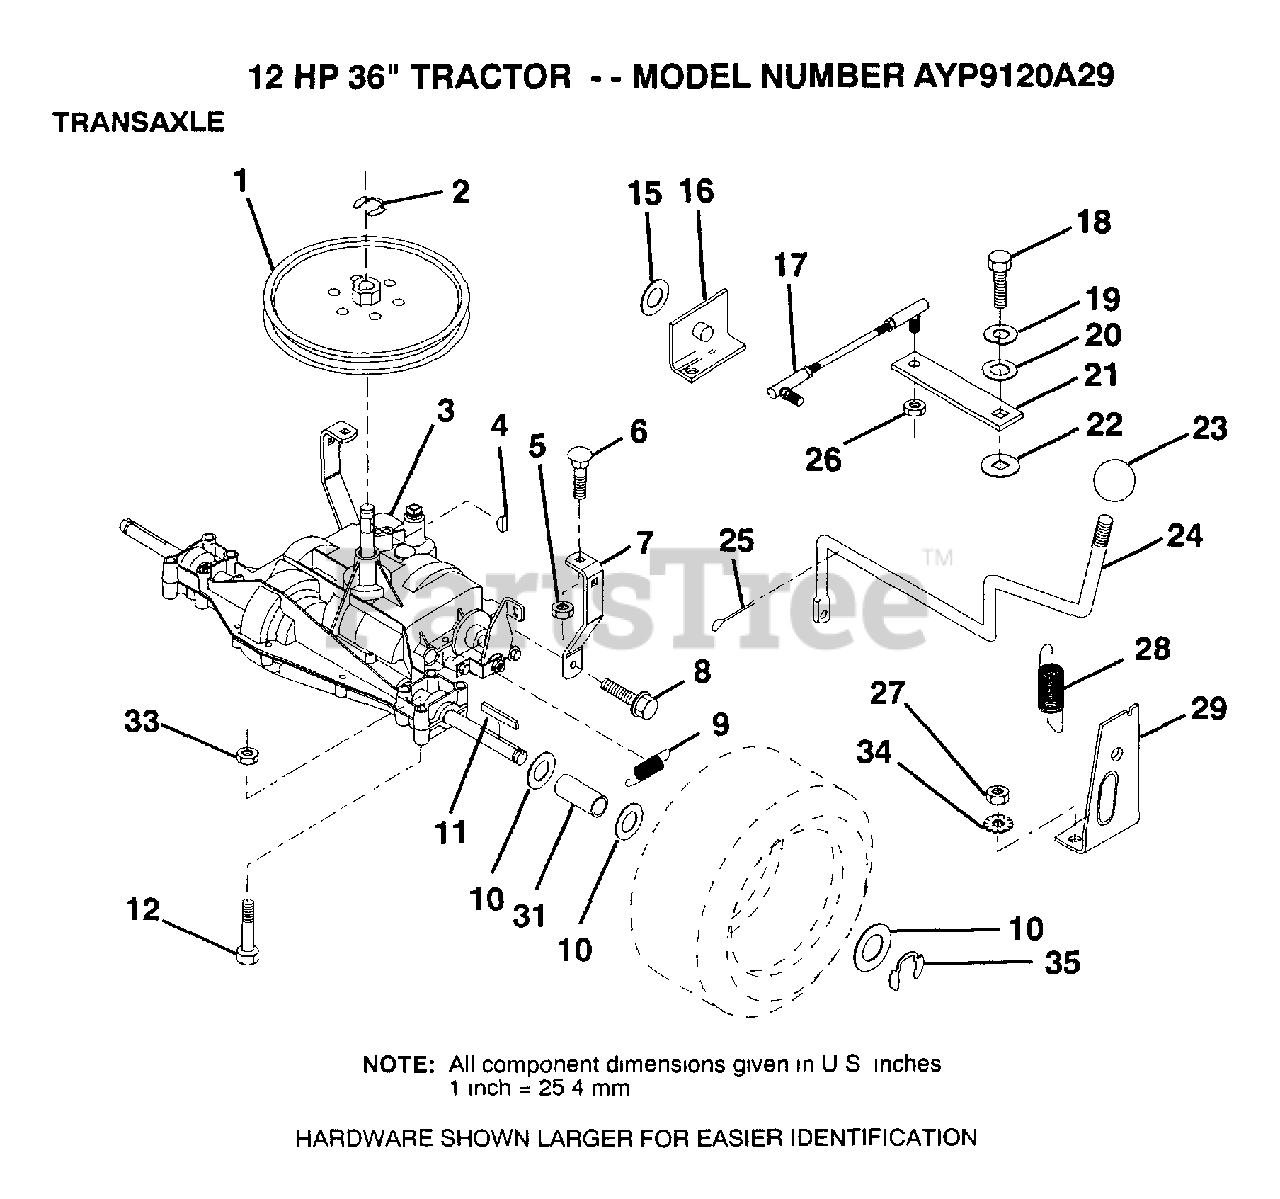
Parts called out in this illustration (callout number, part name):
1	PULLEY
6	BOLT
7	"STRAP,TORQUE"
8	SCREW
10	WASHER
11	SQUARE KEY
12	BOLT
13	"BRKT,TRANSAXLE"
16	"SUPT,HDLE SHT LH"
17	"LINK,SHIFT"
19	LOCKWASHER
20	WASHER LT
21	ARM SHIFT
22	WASH-SHFT PLT LT
23	KNOB T (1/2-HOLE)
24	"ROD,SHIFT"
25	PIN COTTER 1/8
26	NUT.LOCK.5/16-24
28	"SPRING,EXT"
29	"SUPT,HDLE RH"
31	SPACER
34	LOCKWASHER.5/16.E
35	E-RING LT
